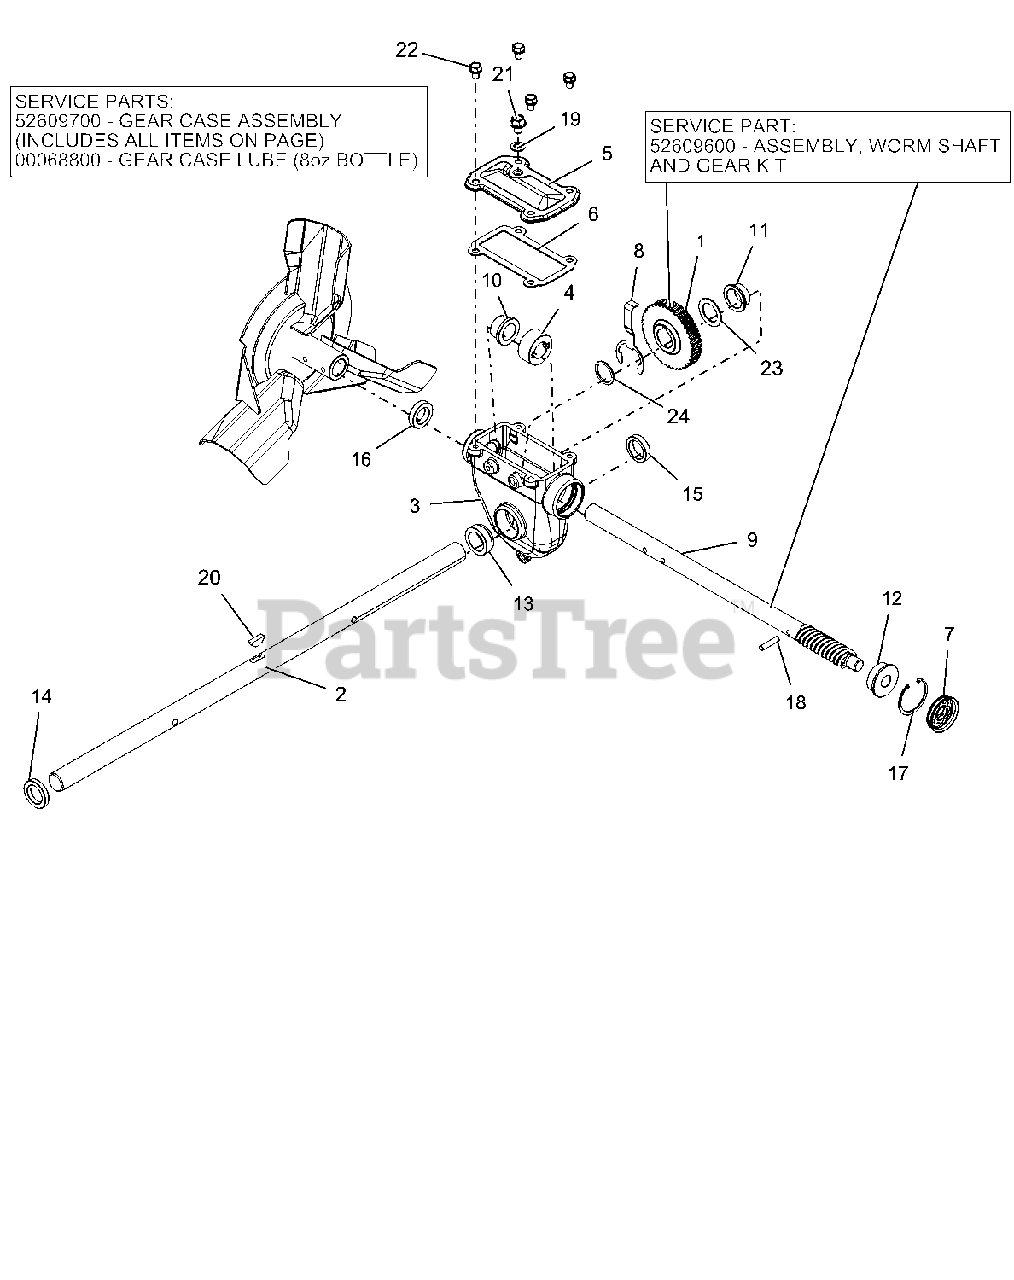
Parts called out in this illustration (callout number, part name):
1	WORM GEAR
2	SHAFT, RAKE-28"
3	GEARCASE, LARGE MACHINED
4	THRUST COLLAR, .875"ID SLIPFIT
5	COVER, TOP - LARGE IRON
6	GASKET, TOP - LARGE GEARCASE
7	COVER, GEAR CASE 1.75"
8	BUSHING RETAINER, LARGE
9	SHAFT, WORM - PRO
10	BSHG-FLG .879X1.128X.75X1.45
11	BSHG-FLG 1.006X1.128X.555X1.45
12	BSHG-FLG .628X1.503X.58X1.725
13	BSHG-FLG LARGE, RIGHT
14	SEAL-OIL .999X1.500X.250 TBC29
15	SEAL-OIL .999X1.375X.312 TBC29
16	SEAL-OIL .873X1.375X.312 TBC29
17	RG-RTNG-INT 1.750X.062
18	PIN-STR .250X1.12 6150
19	WSHR-BND-SEAL .38X.75X.11 GALV
20	KEY-WDRF .25X.875 HRD #A
21	@SCR-ROLOK .38-16X.50 HWH YWZC
22	BOLT, SEMS .31-18X.50 GR5 YWZC
23	WSHR-FL-STL 1.010X1.505X.062YZ
24	WSHR-FL-STL 1.010X1.250X.068YZ
25	GEAR CASE, 28" IRON PRO TOP-LD
26	ARIENS L3 LUBE, 8 OZ BOTTLE
27	ASSY, WORM SHAFT & GEAR
